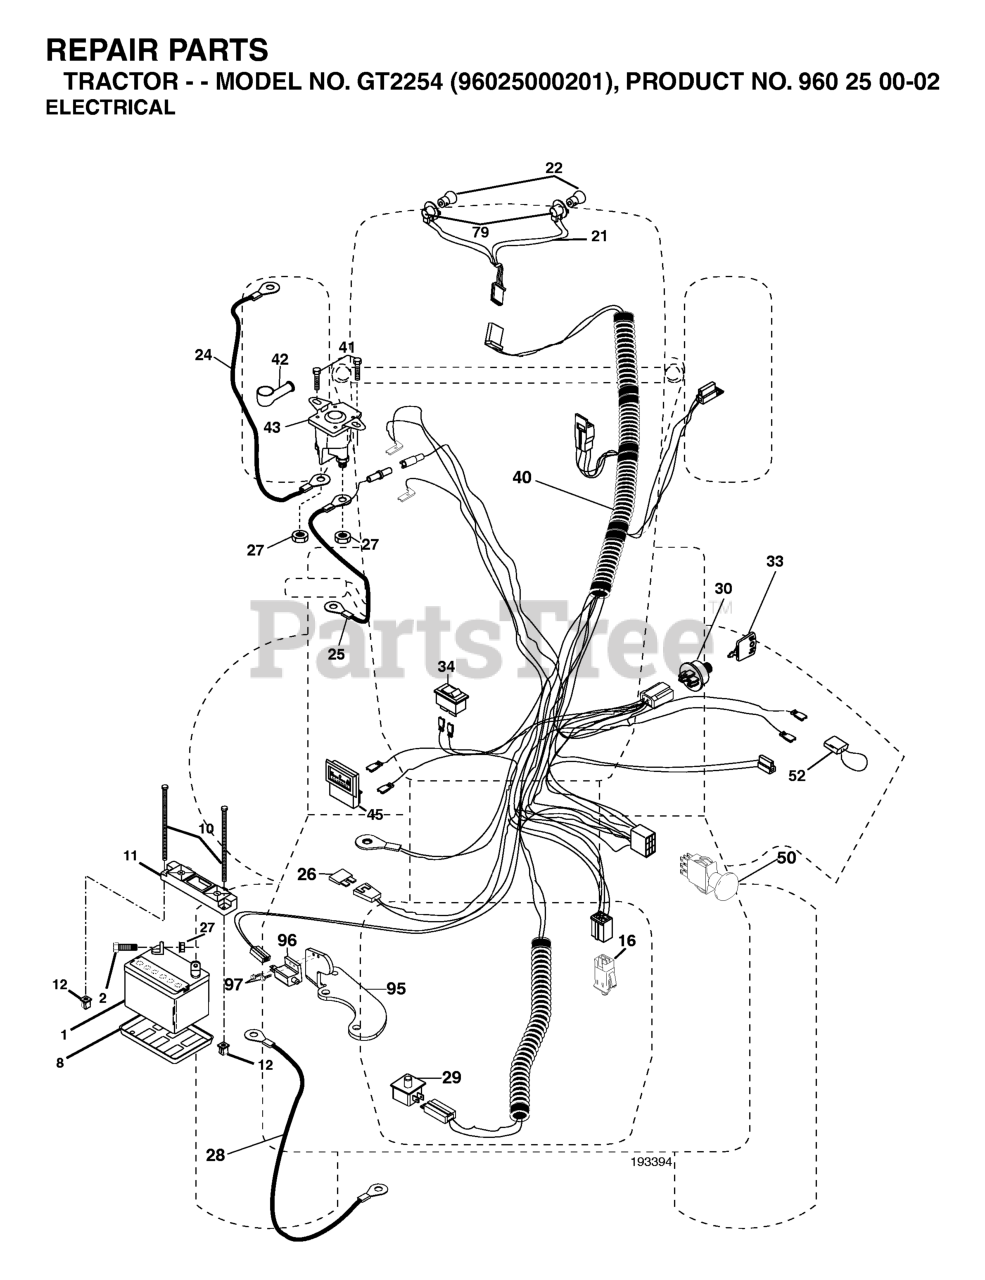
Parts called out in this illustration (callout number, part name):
1	BATTERY 12V .35 AMP
2	BOLT.HEX.1/4.X.3/4.DICHROMATE
8	BATTERY TRAY T
10	BOLT 1/4-20 X 7.5
11	BATTERY HOLDDOWN FRONT MOUNT
12	NUT, PUSH NYLON 1/4" BATTERY
16	SWITCH INTERLOOK PUSH-IN
21	HARNESS.W/LIGHT SOCKET
24	CABLE.STARTER.6GA.22"RED
25	CABLE, BATTERY
27	NUT
28	CABLE, GROUND
29	SWITCH.SEAT.DP W/RAMPS
30	SWITCH.IGN.DELTA.W.LGH.ROS
33	KEY MLD GEN DELTA
40	HARNESS.IGN.REG.RECT
41	SCREW
42	TERMINAL COVER
43	SOLENOID
50	RP.SWTICH.PTO.8.TERMINAL
52	WIRE PROTECTION LOOP
79	BULB HOLDER ASM.
95	BRKT.ROS.6SP
96	SWITCH-INTER. GT
97	SCREW.TT.#10-32X.5.3/8.FLANGE
